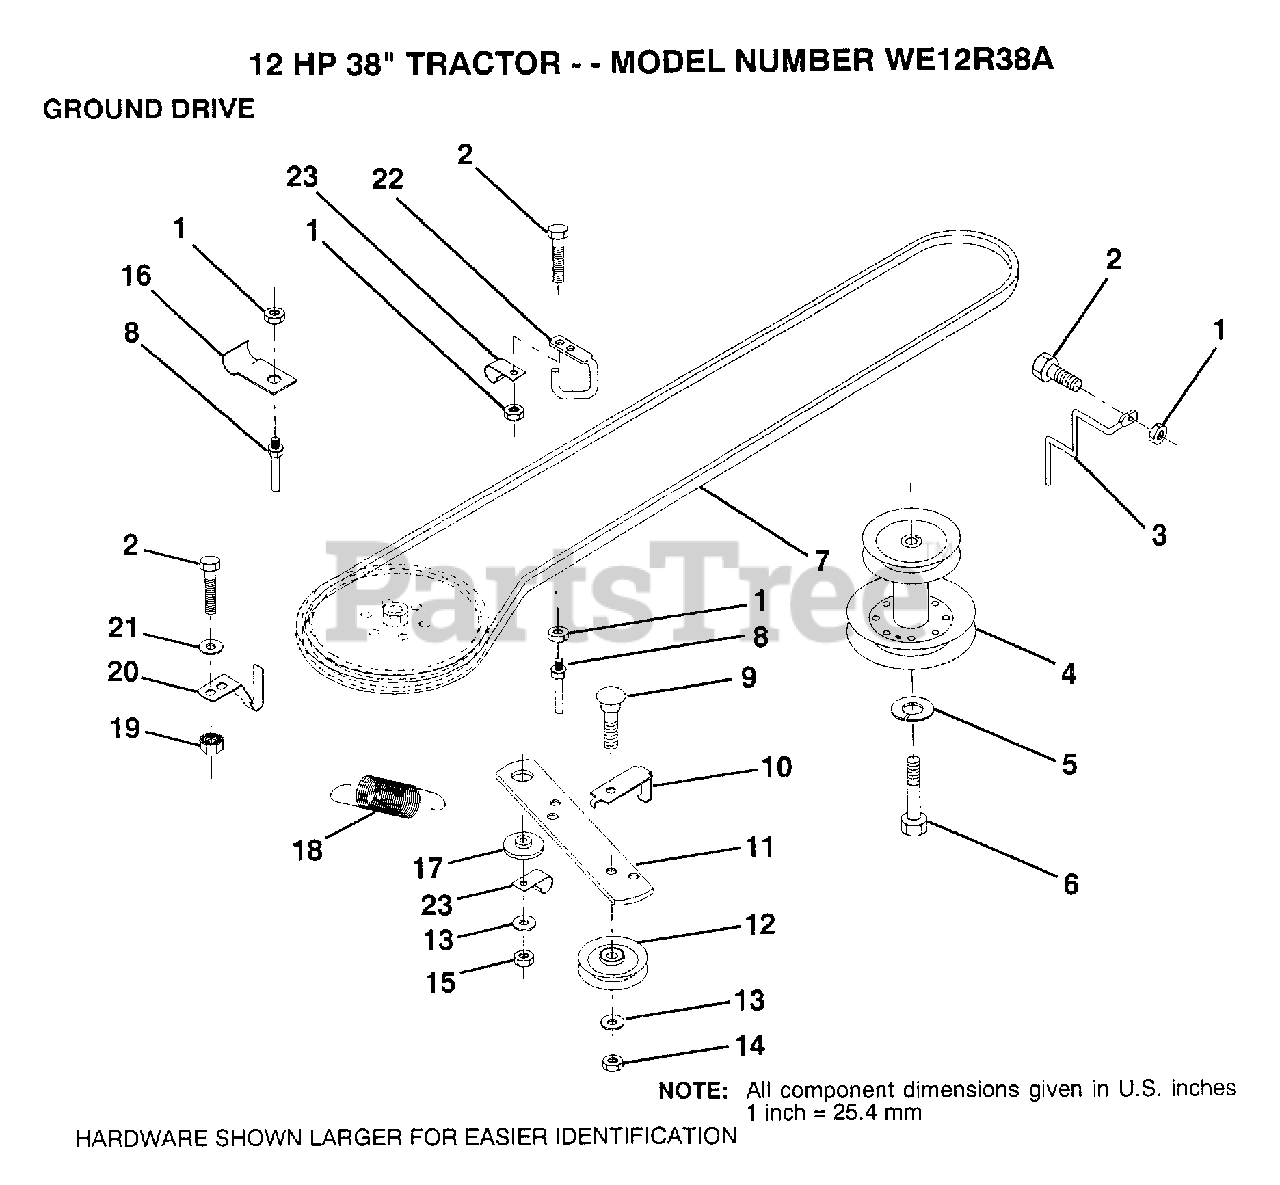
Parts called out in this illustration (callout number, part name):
2	BOLT
3	KEEPER MWR DR BLT
5	LOCKWASHER
6	BOLT
7	BELT
8	"KEEPER,DRIVE BELT"
9	BOLT
10	"KEEP,IDLER DR BEL"
12	PULLEY.IDLER.FLAT
13	WASHER
14	LOCKNUT
16	"CLIP,INSULATOR"
17	SPACER RETAINER
20	"KEEPER,DR BELT "
21	WASHER
22	"KEEPER,FRA DR BEL"
23	CLIP INSULATOR
